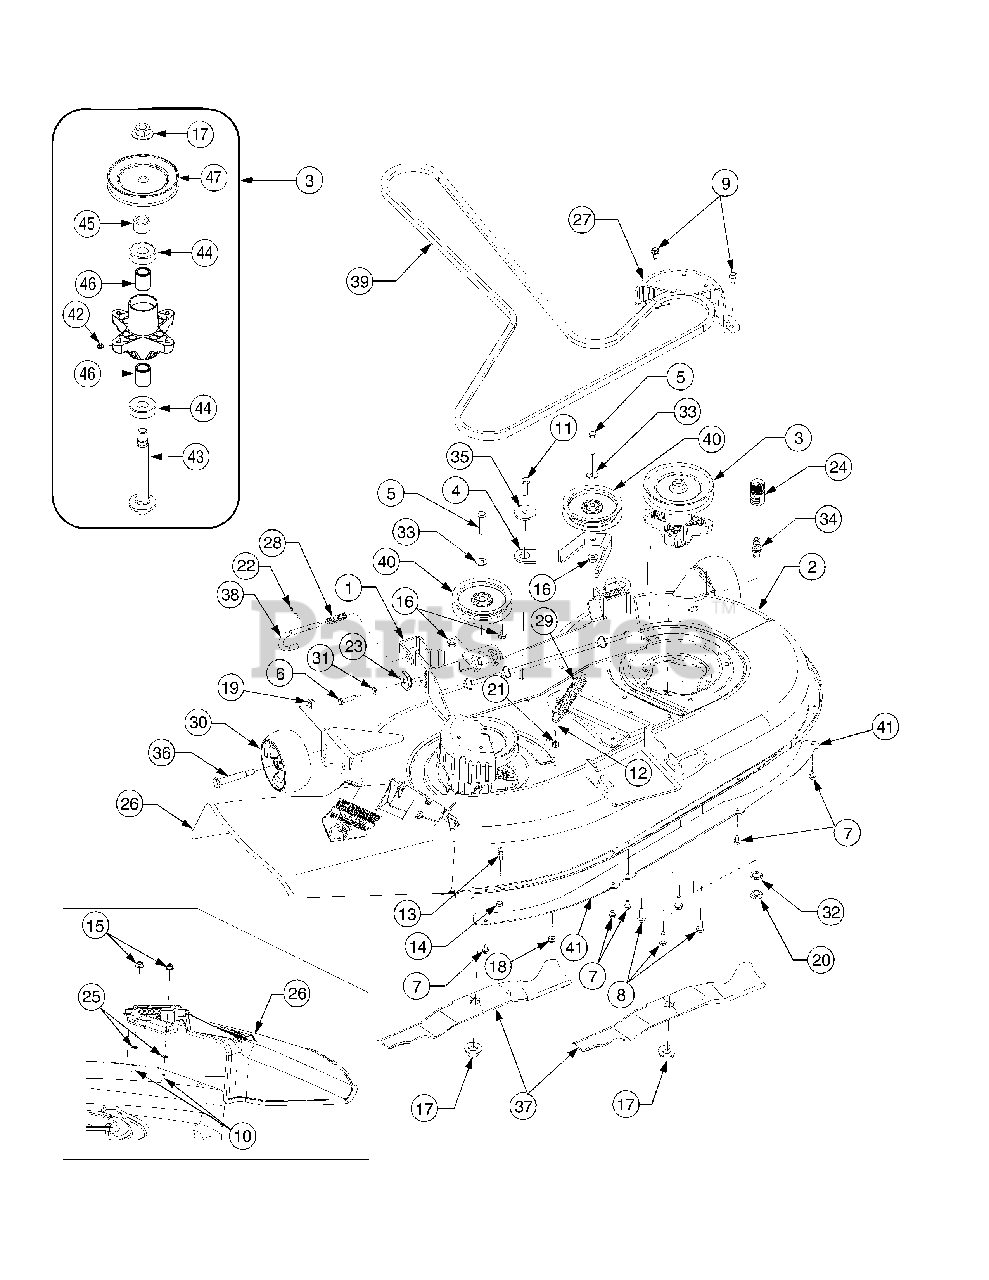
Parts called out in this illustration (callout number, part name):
1	Deck Lift Bracket
2	Deck Housing
3	Spindle Assembly
4	Idler Arm
5	Hex Screw 3/8-16 x 1.75
6	Hex Bolt 5/16-18 x 1.25
7	Hex Wash S-Tapp Scr 1/4-20 x .50
8	Hex Wash. Hd. Scr. 5/16-18 x .75 Lg.
9	Hex Wash HD AB Tap Scr 5/16-12 x .75
10	Hex Bolt 1/4-20 x .62 Gr. 5
11	Hex Bolt 3/8-16 x 1.25
12	Hex Screw 5/16-18 x 1.75" Lg.
13	Grasscatcher Pin 1/4-20
14	Hex Ins. Locknut 1/4-20
15	Hex L-Flanged Nut 1/4-20 Gr. F Nylon
16	Flange Lock-Nut 3/8-16 Gr. F Nylon
17	Hex Flange Nut 5/8-18
18	Hex Ins. L-Nut 5/16-18
19	Hex. Flanged L-Nut 3/8-16 Gr. F
20	Hex Nut M16-1.5 DIN 936
21	Hex Nut 5/16-18 hd. (Gr. 5)
22	Cotter Pin 1/8" Dia x 1.25
23	Deck Adjustment Gear
24	Water Nozzle Adaptor
25	Bolt Retainer 1/4" x .50" OD
26	Chute Deflector (Plas tic)
28	Compression Spring
29	Extension Spring .94 OD x 6.74
30	Deck Wheel 5.0
31	L-Wash 5/16 ID
32	L-Washer Internal
33	Flat Washer .38 x .93 x .11
35	Shoulder Spacer .884 x .190
36	Shoulder Screw, 1/2 Diameter x 2.5
37	Blade 21.23" lg.
38	Deck Release Pin
39	V-Belt Type A Sec x 114.1
40	Idler Pulley w/Flange 4.25 Dia
42	Grease Fitting
43	Spindle Shaft 5.75
44	Ball Bearing 20 x 47 x 14:6204:DS
45	Spacer .820 x 1.150 x .730 Lg.
46	Spacer .080 x 1.10 x 1.322" Lg.
47	Deck Pulley 6.3 Dia.
